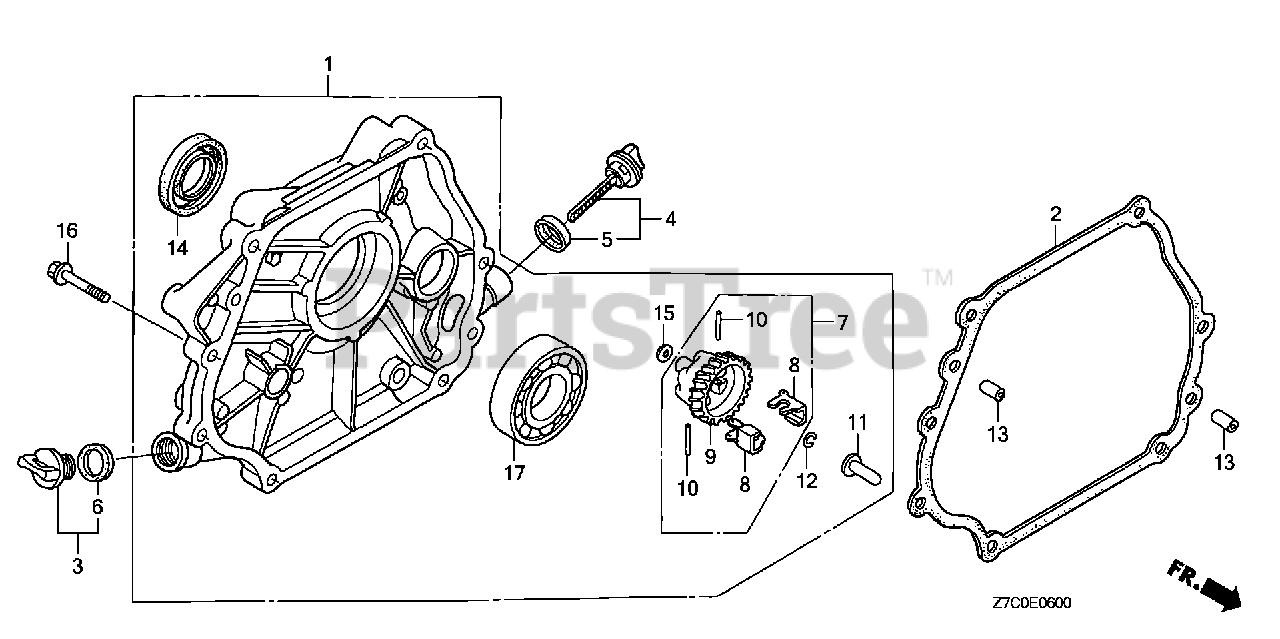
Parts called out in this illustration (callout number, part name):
1	COVER ASSY., CRANKCASE
2	GASKET, CASE COVER
3	CAP ASSY., OIL FILLER
4	CAP ASSY., OIL FILLER
5	GASKET, OIL FILLER CAP
6	GASKET, OIL FILLER CAP
7	GOVERNOR ASSY.
8	WEIGHT, GOVERNOR
9	HOLDER, GOVERNOR WEIGHT
10	PIN, GOVERNOR WEIGHT
11	SLIDER, GOVERNOR
12	CLIP, GOVERNOR HOLDER
13	PIN, DOWEL (8X12)
14	OIL SEAL (30X46X8)
15	WASHER, PLAIN (6MM)
16	BOLT, FLANGE (8X35)
17	BEARING, RADIAL BALL (6206)
